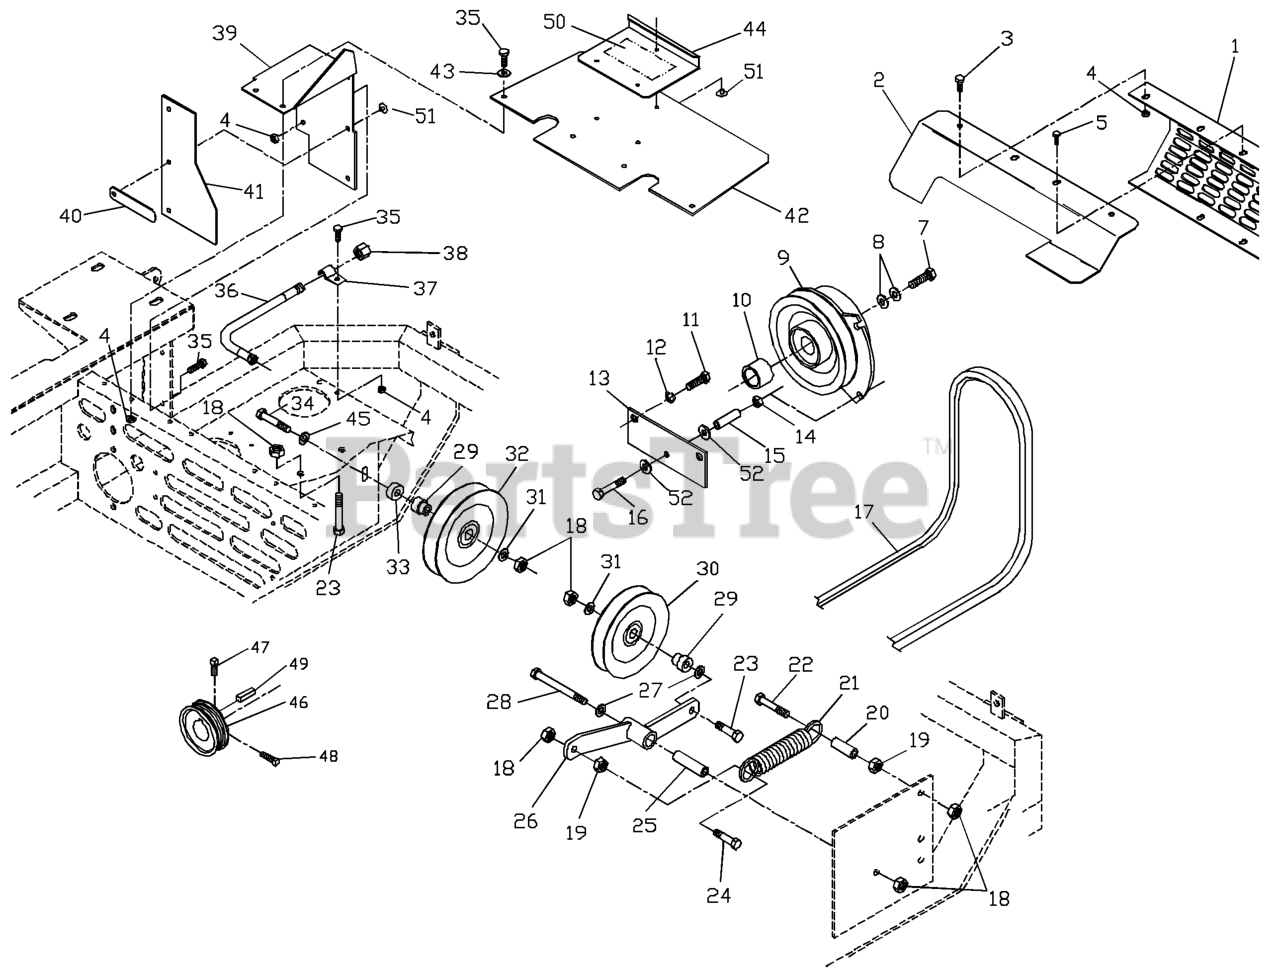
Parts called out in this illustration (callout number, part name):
1	MUFFLER SHIELD
2	HEAT DEFLECTOR
3	HCS 1/4C X 5/8
4	NUT 1/4C CENTERLOCK
5	HEX CAP SCREW M6 X 1MM X 10MM
7	BOLT 7/16F X 2 1/2
8	WASHER, 7/16 DISC SPRING
9	CLUTCH/BRAKE-GEN I
11	HCS 7/16-14 X 1 GR 5 ZD
12	WASHER 7/16 LOCK
13	CLUTCH STOP PLATE
14	NUT 5/16C CENTERLOCK
16	BOLT 5/16C X 3 1/4 HEX TAP
17	BELT, MULE DRIVE
18	NUT 3/8C CENTERBLOCK
19	NUT 3/8C WHIZ
22	HCS 3/8C X 2 1/2
23	HCS 3/8-16 X 1 3/4 GR5
24	HCS 3/8C X 2 1/4
26	ARM WELDMENT
27	WASHER 3/8 FLAT
28	HCS 3/8C X 3
29	SHOULDER BUSHING
30	IDLER PULLEY
31	WASHER 3/8 SAE FLAT
32	IDLER PULLEY
34	SCREW 3/8C X 2 3/4 HEX CAP
35	HCS 1/4C X 3/4 HCS
36	OIL DRAIN HOSE
39	ENGINE BAFFLE, LEFT
40	SHIELD CLIP
41	HEAT SHIELD
42	ENGINE SHIELD/COMPLETE
43	WASHER 1/4 FLAT
44	LIFT SHIELD
45	WASHER, 3/8 DISC SPRING SPEC
46	ENGINE PULLEY
47	SCREW 5/16C X 5/8 SQ HEAD
48	SCREW, HEAD SET 5/16C X 3/4 SQ
49	KEY, 1/4 SQ X 1 1/4
50	DECAL, DANGER
51	RIVET E/16 X 1/4 LG FLG
52	WASHER 5/16 FLAT
